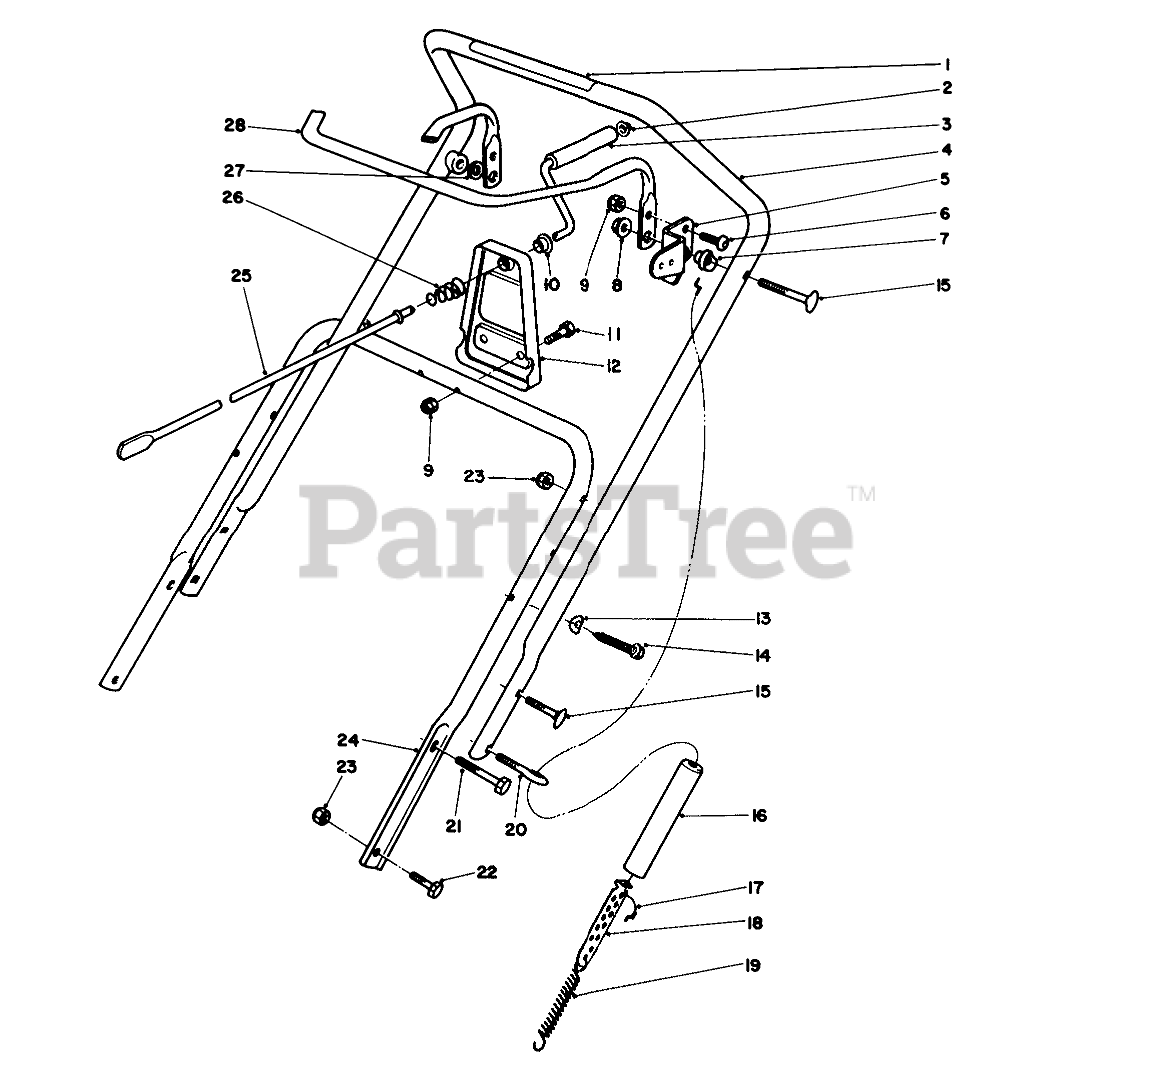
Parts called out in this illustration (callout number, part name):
1	DECAL - ROTOR DRIVE
2	RETAINER-PUSH ON
3	Grip-Rod
4	Upper Handle Assembly (Incl. Ref. #1, Model 38180)
5	Arm-Clutch Cable
6	SCREW-HSBH
7	SPACER-BAR, CONTROL
8	NUT-LOCK, CAP
9	NUT-LOCK, NI
10	Bushing
11	SCREW-HH
12	Support-Crank
13	WASHER
14	SCREW
15	SCREW
16	COVER-SPRING
17	CABLE-CLUTCH
18	ADJUSTER-CABLE
19	SPRING-EXTENSION
20	BOLT-EYE
21	SCREW-HH
22	SCREW-HH
23	NUT-LOCK, NI
24	Handle-Lower (Model 38180)
25	ROD-CRANK, CHUTE
26	SPRING-COMPRESSION
27	WASHER
28	Bar-Control
